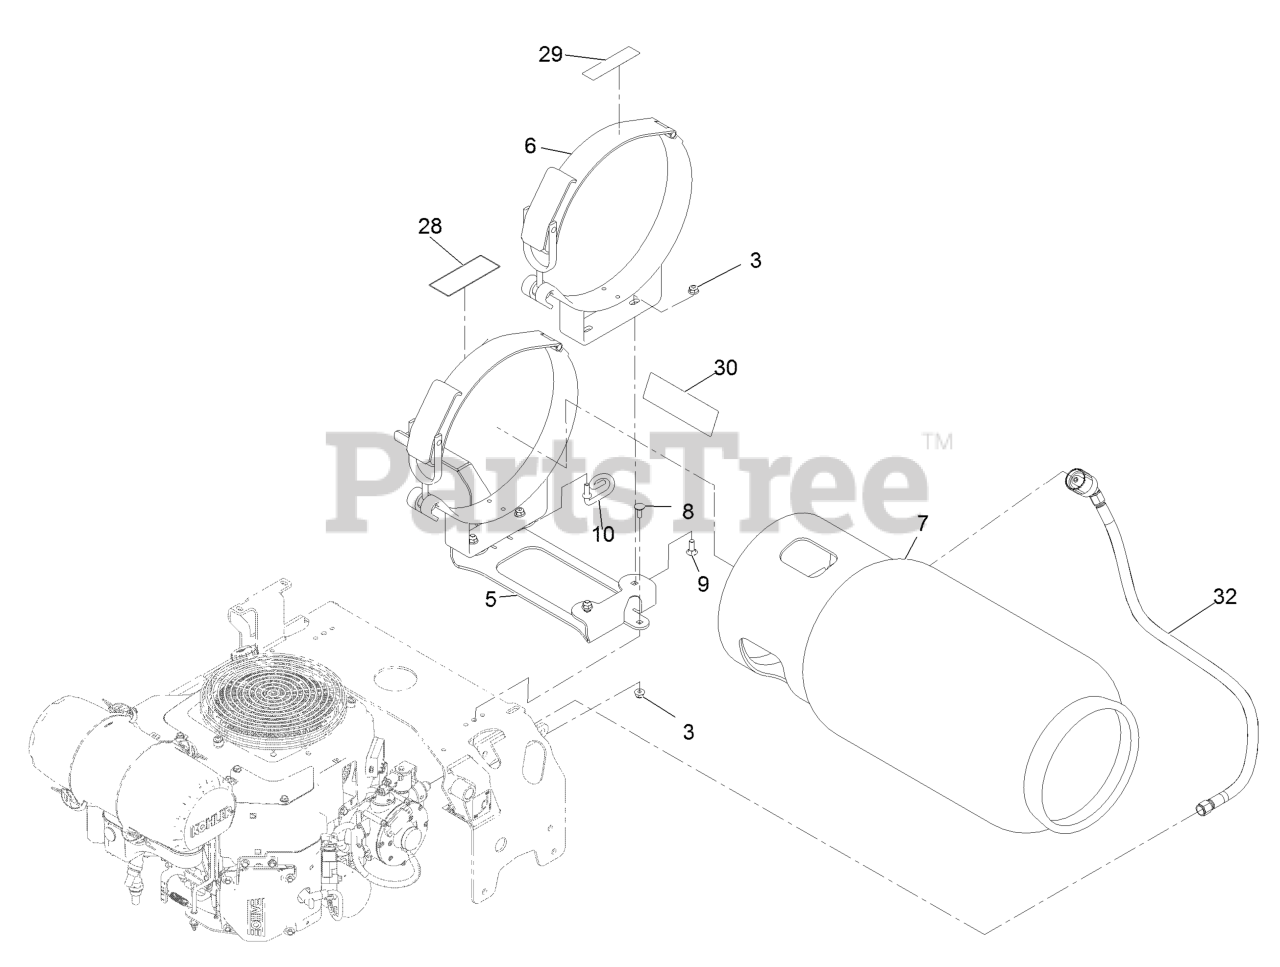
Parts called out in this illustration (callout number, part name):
3	NUT-HF, NI
5	WELD, TANK MOUNT
6	BRACKETS, LPG TANK - HORI
7	TANK, LP - 33.5 LB.HORIZO
8	SCREW-CARR
9	SCREW-CARR
10	RETAINER, LP HOSE
28	Decal-LPG Warning
29	Decal-LPG Horiz Tank Spec
30	Decal-LPG Fuel Tank Replacement
